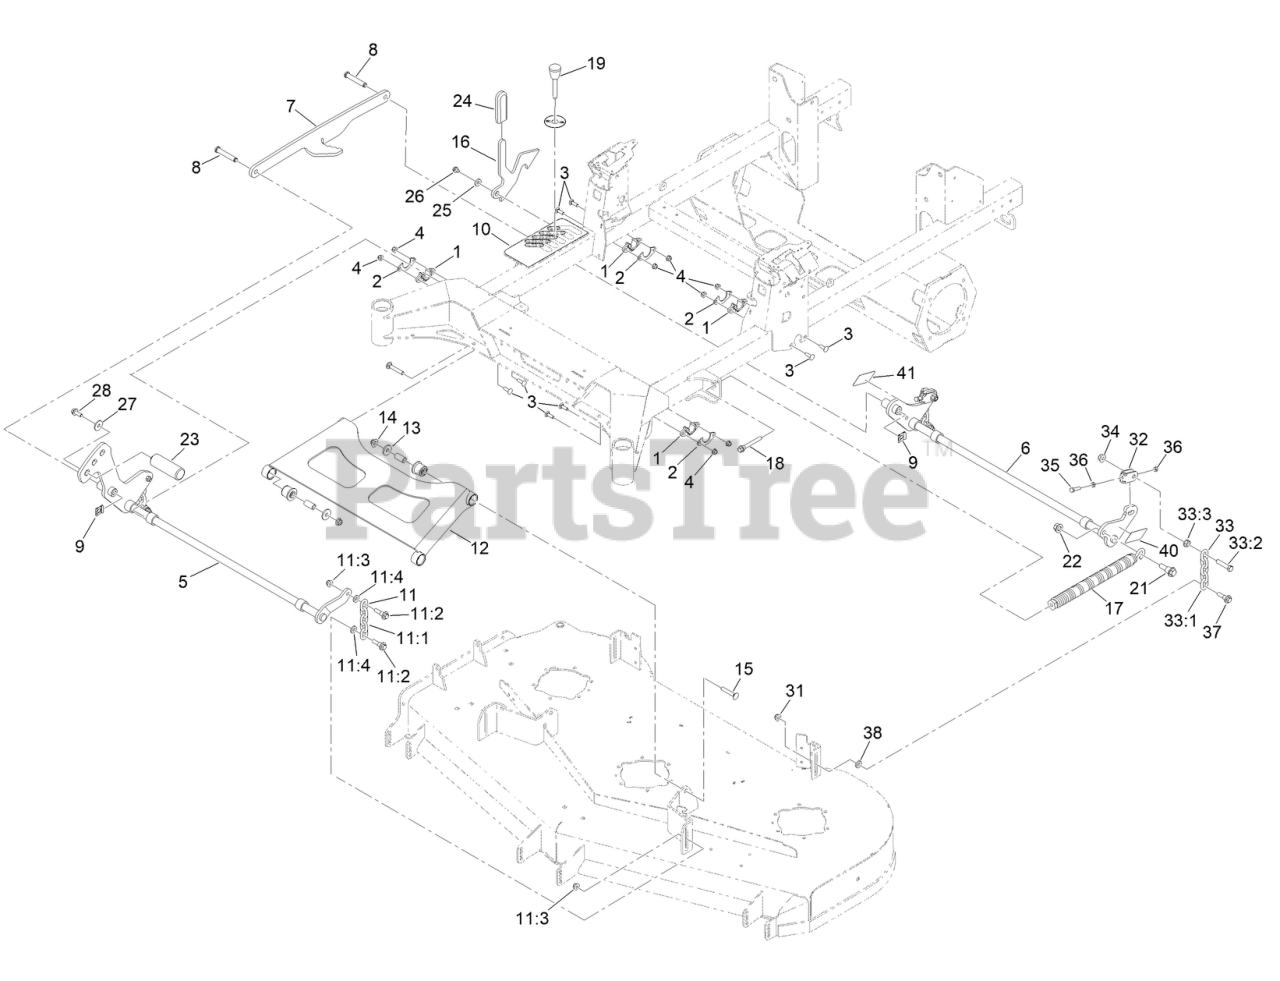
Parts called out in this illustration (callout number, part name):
1	BEARING-FLANGE
2	GUSSET-LIFT, DECK
3	SCREW-CARR
4	NUT-HF, NI
5	DECK LIFT SHAFT ASM, FRT [BLACK
6	ADJ DECK LIFT SHAFT ASM
7	LINK-LIFT
8	PIN-CLEVIS
9	CLIP-PIN
10	DECAL-HOC
11	DECK CHAIN ASM
11:1	CHAIN-LIFT, DECK
11:2	BOLT-SHOULDER
11:3	NUT-HF, NI
11:4	SPACER
12	ASM-DECK STRUT W/ BUSHINGS
13	WASHER
14	NUT-FLANGE, NI
15	SCREW-CARR
16	PLATE-TRANSPORT LOCK
17	SPRING-EXTENSION
18	BOLT-SHOULDER
19	PIN-HOC
21	SCREW-SHOULDER, HHF
22	NUT-LOCK
23	PEDAL-FOOT LIFT
24	GRIP-LEVER
25	SPACER
26	SCREW
27	WASHER
28	SCREW-HHF
31	NUT-HF, NI
32	YOKE-ADJUST, DECK
33	DECK LIFT CHAIN ASM
33:1	CHAIN-LIFT, DECK
33:2	SCREW-HH
33:3	NUT-HF
34	NUT-HF, NI
35	SCREW-HH
36	NUT-JAM
37	BOLT-SHOULDER
38	SPACER
40	DECAL-RAKE, LH
41	DECAL-RAKE, RH
